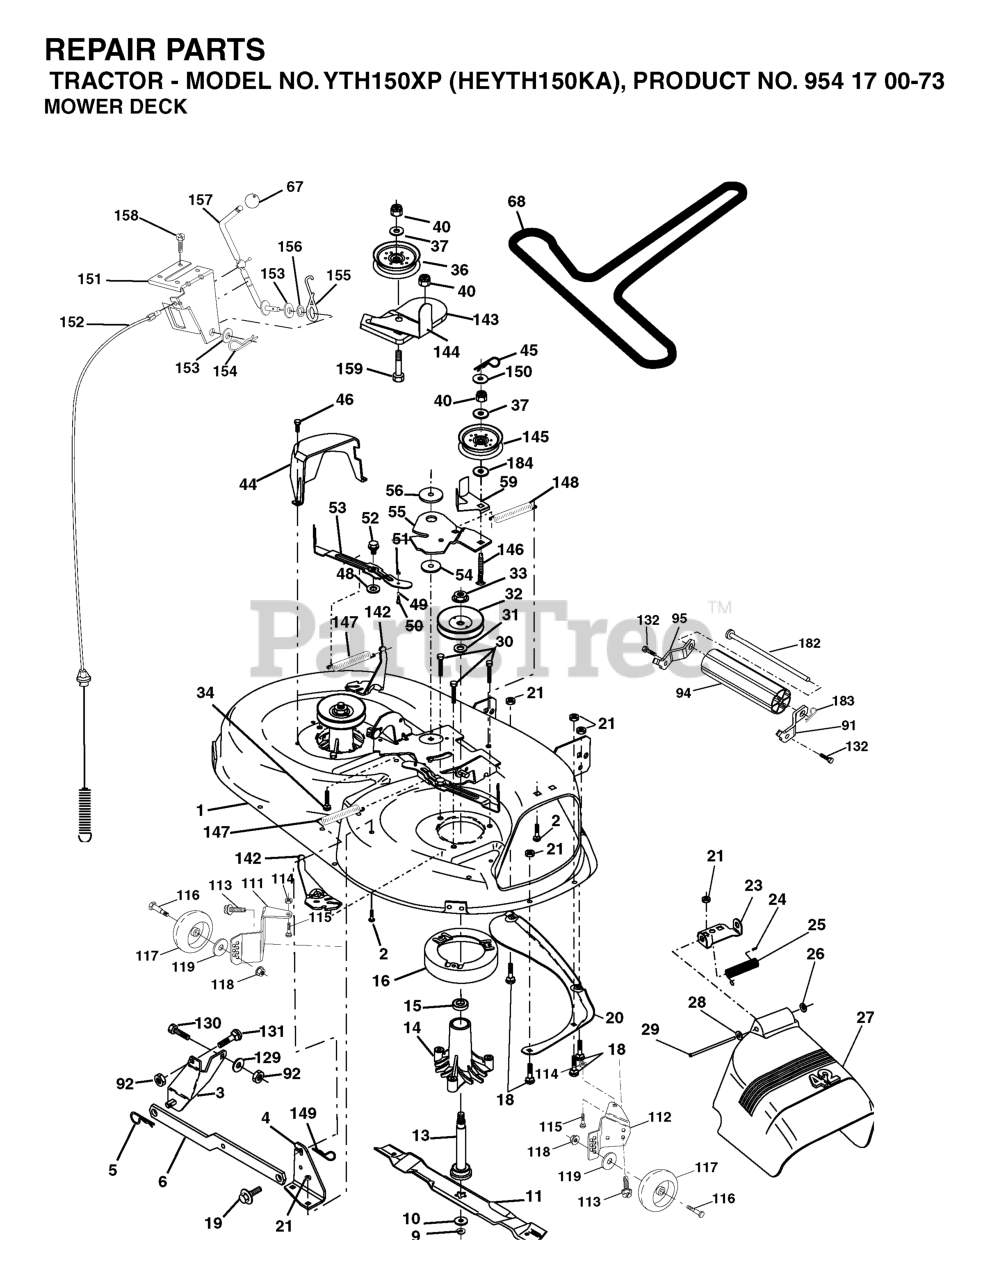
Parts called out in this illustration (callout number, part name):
1	42" DECK KIT
2	RP BOLT 5/16-18 X3/4 ZN/YEL GR
3	BRKT ASM SWAY BAR
4	BRACKET SWAY BAR 42" DECK
5	RETAINER-SPRNG RB
6	BAR SWAY DECK
8	BLADE BOLT
9	LOCKWASHER
10	WASHER.BLADE
11	Blade Mower 42" High Perf.
13	SHAFT ASM VENT
14	HOUSING.MANDREL.VENTED (MACHD)
16	STRIPPER.MANDREL.ROUND.BLACK
18	BOLT
19	BOLT SHD 5/16-18
20	BAFFLE.VORTEX
21	LOCKNUT
23	BRKT, DEFL. MOWER
24	CAP-SLEEVE LT
25	SPRING TORSION
26	NUT PUSH M
27	SHIELD DEFLECTOR
28	Washer 11/32 x 5/8 x 16 Ga SD
29	ROD.HINGE
30	SCREW, WASHER HEAD
31	WASHER
32	PULLEY/MANDREL
33	NUT, FLG TOPLOCK 9/16"
36	FLAT IDLER PULLEY
37	WASHER
44	GUARD MANDREL LH BLACK
45	RETAINER M
46	SCREW.1/4-20X5/8
52	BOLT.SHOULDER.5/16-18
53	ARM BRAKE ASSY
55	ARM IDLER 42" MOWER LT/YT
56	SPACER.RETAINER.MOWER
59	GUARD, BELT
67	KNOB T (3/8 HOLE)
91	BRACKET ASM NOSEROLLER LH
92	NUT
94	NOSE ROLLER
95	BRACKET ASM NOSEROLLER RH
111	BRACKET, WHEEL
112	BRACKET, WHEEL
113	Screw Tapping 3/8-16 x .625
114	NUT
115	BOLT.CARR.5/16-18X5/8.SHORT
116	BOLT M
117	WHEEL.GAUGE.STANDARD
118	LOCKNUT
119	WASHER.5/16.FLAT.STE.STD.
129	WASHER
130	BOLT
131	BOLT D
132	SCREW, 3/8-16X3/4
142	ARM SPRING BRAKE MOWER
143	BRACKET, ARM IDLER
144	DNO KEEPER.BELT.42".CLUTCH.CBL
145	PULLEY
146	BOLT, CARRIAGE IDLER BLACK
148	IDLER RETURN SPRING
149	SPRING.RETAINER.YELLOW.ZINC
150	WASHER PM
151	BRACKET.CLUTCH.CABLE
152	CABLE.CLUTCH.42"
153	WASHER FLAT 3/8"
154	SPRING RETAINER
155	SPRING RETENTION LEVER
156	SPACER.CLUTCH.CABLE
157	ROD CLUTCH CABLE 3/8"
158	SCREW
159	BOLT
182	ROD ROLLER NOSE STANDARD
183	SPRING RETAINER
184	WASHER
